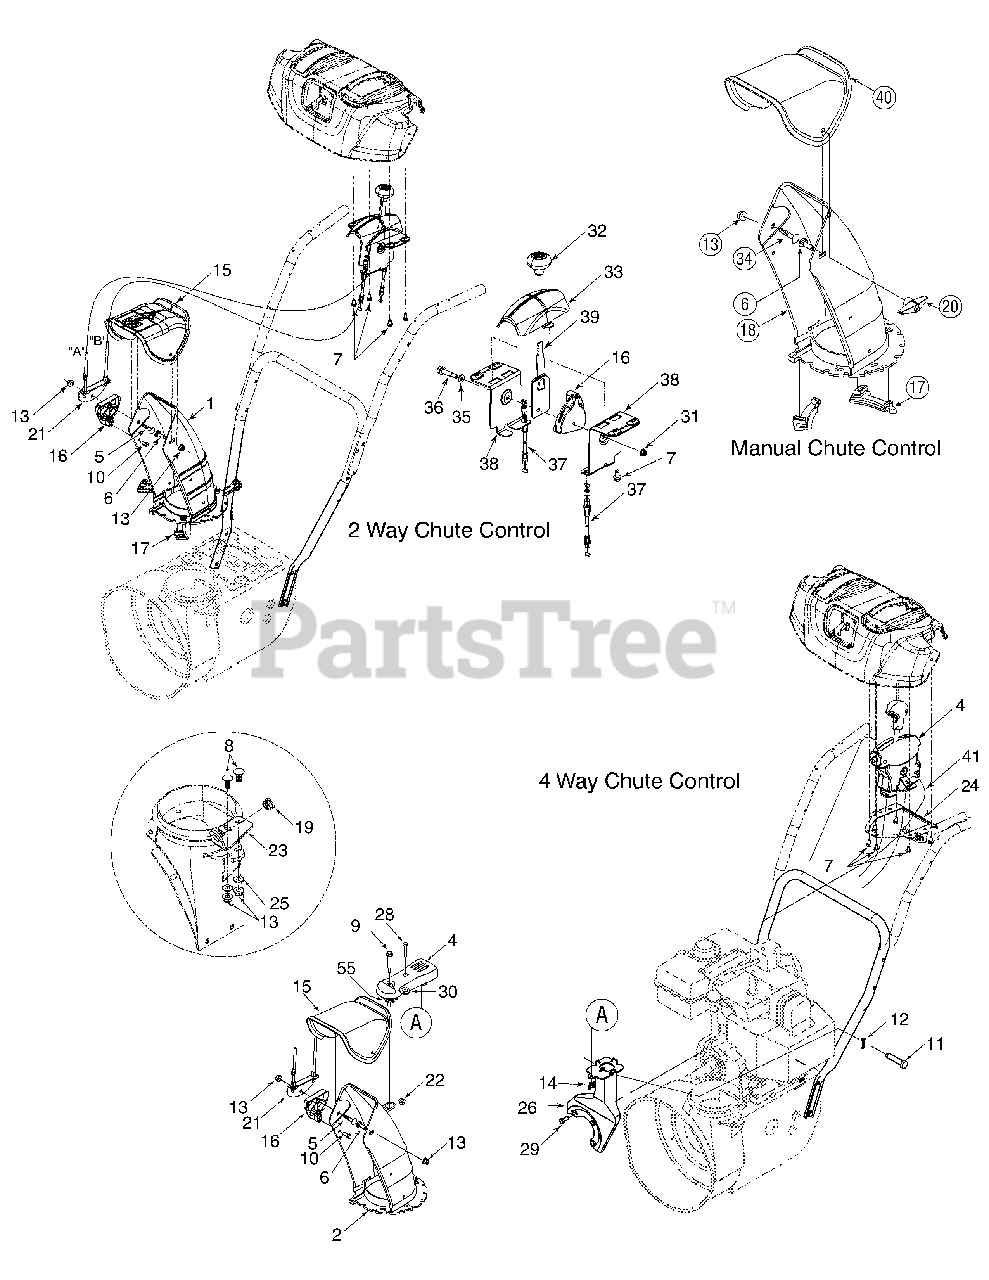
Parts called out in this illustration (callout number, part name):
1	Lower Chute (2 Way)
2	Lower Chute (4 Way)
3	2 Way Chute Control Assembly
4	4 Way Chute Control Assembly
5	Carriage Bolt 5/16-18 x 1.50 Gr. 2
6	Carriage Screw 5/16-18 x 1.0
7	Hi-Lo Screw 1/4-15 x .5
8	Carriage Bolt 5/16-18 x 1.00" Lg
9	Shoulder Screw .312 x 1.7:1/4-20
10	Hex Tapp Scr 1/4 x .75" Lg.
11	Clevis Pin 3/8 x 1.87
12	Bow Tie Cotter Pin
13	Flange Locknut 5/16-18 Gr. F Nylon
14	Wing Nut 1/4-20
15	Upper Chute w/Export Label, Remote
17	Chute Flange Keeper
19	Plastic Bushing .380 ID
20	Handle Knob Assembly
22	Hex L-Flanged Nut 1/4-20 Gr. F Nylon
25	Flat Washer .349 ID x .879 OD x .063
28	Hex Hd. Cap Screw 1/4-20 x 1.5 Gr. 5
29	Hex Hd. Cap Screw 5/16-24 x .75
30	Flat Washer .25 ID x .63 OD x .0515
31	Flange Locknut 1/4-20 Gr. F, Nylon
33	Control Cover - 2 Way
34	Carriage Bolt 5/16-18 x .75
35	Spring Washer .390 x .625 x .012
36	Flg Shlder Spacer .310 x .995 x 1/4-20
37	Cable - 2 Way
